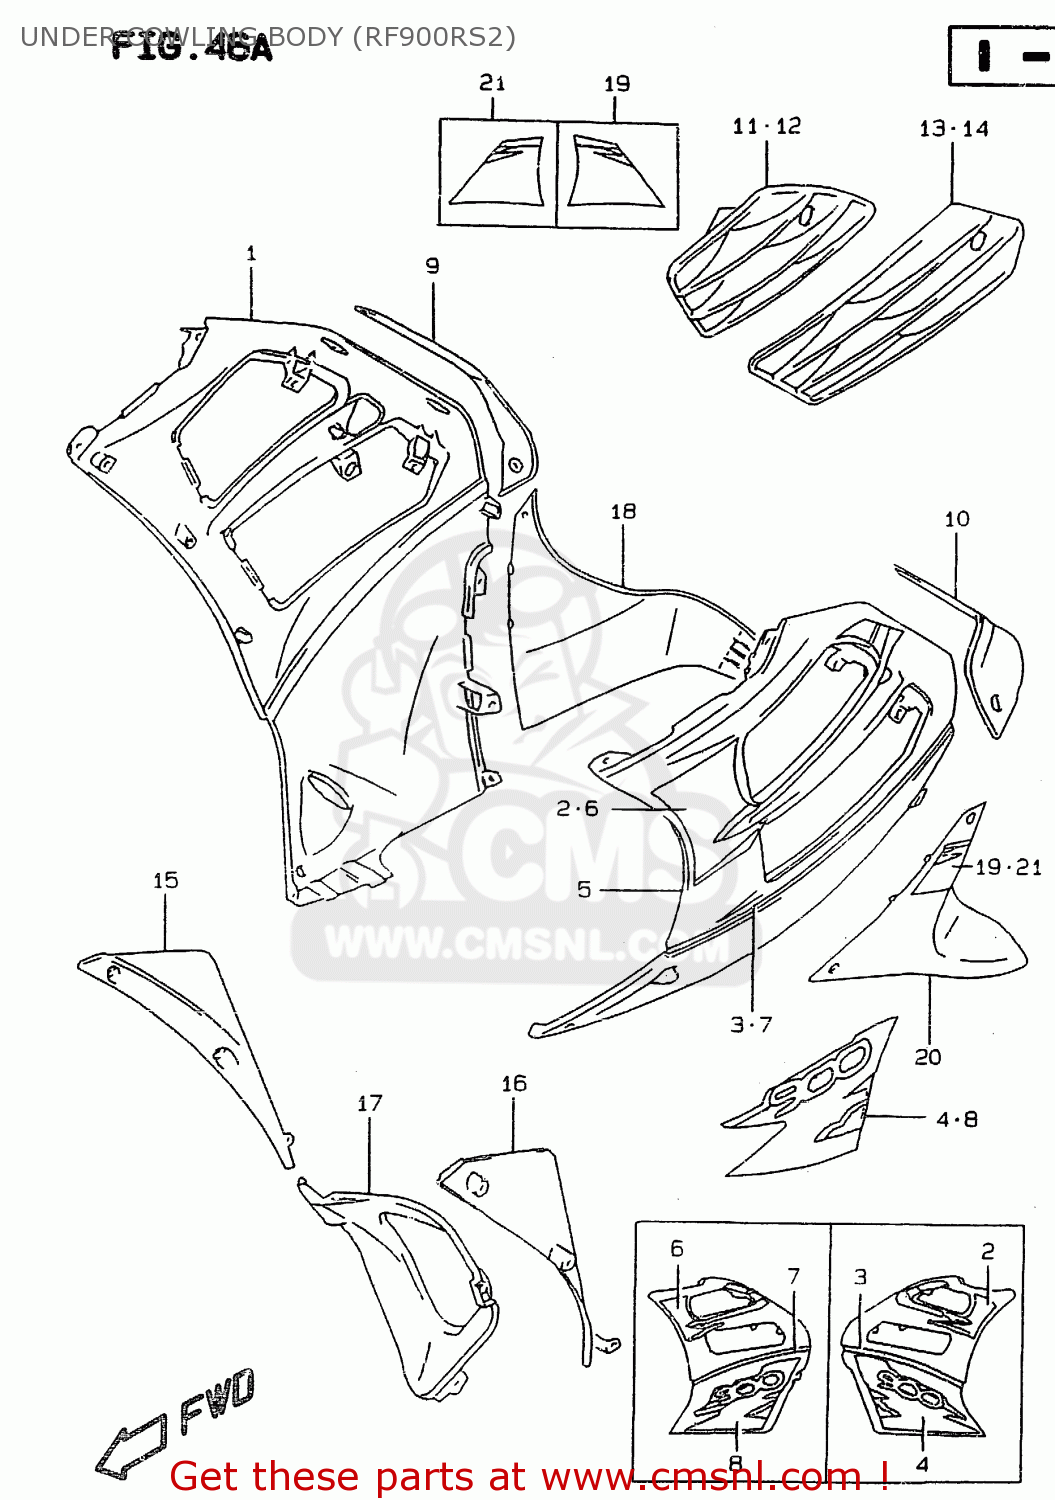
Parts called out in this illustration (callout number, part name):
1	COWLING ASSY,UNDER,R(SILVER)
2	TAPE SET,COWL UNDER UPR,R
3	TAPE,UNDER COWL,R
4	TAPE,COWL UNDER LWR,R
5	COWLING ASSY,UNDER,L(SILVER)
6	TAPE SET,COWL UNDER UPR,L
7	TAPE,UNDER COWL,L
8	TAPE,COWL UNDER LWR,L
9	PANEL,UNDER,R
10	PANEL,UNDER,L
11	COVER,UNDER COWL UPR,R
12	COVER,UNDER COWLING,UPPER,LEFT (
13	COVER,UNDER COWL LWR,R
14	COVER,UNDER COWL LWR,L
15	COWLING,UNDER INNER,R
16	COWLING,UNDER INNER,L
17	COWLING,UNDER CTR
18	COWLING,UNDER RR,R
19	TAPE,COWLING,UNDER,REAR
20	COWLING,UNDER,REAR,LEFT (P
21	TAPE,COWL UNDER RR,L
